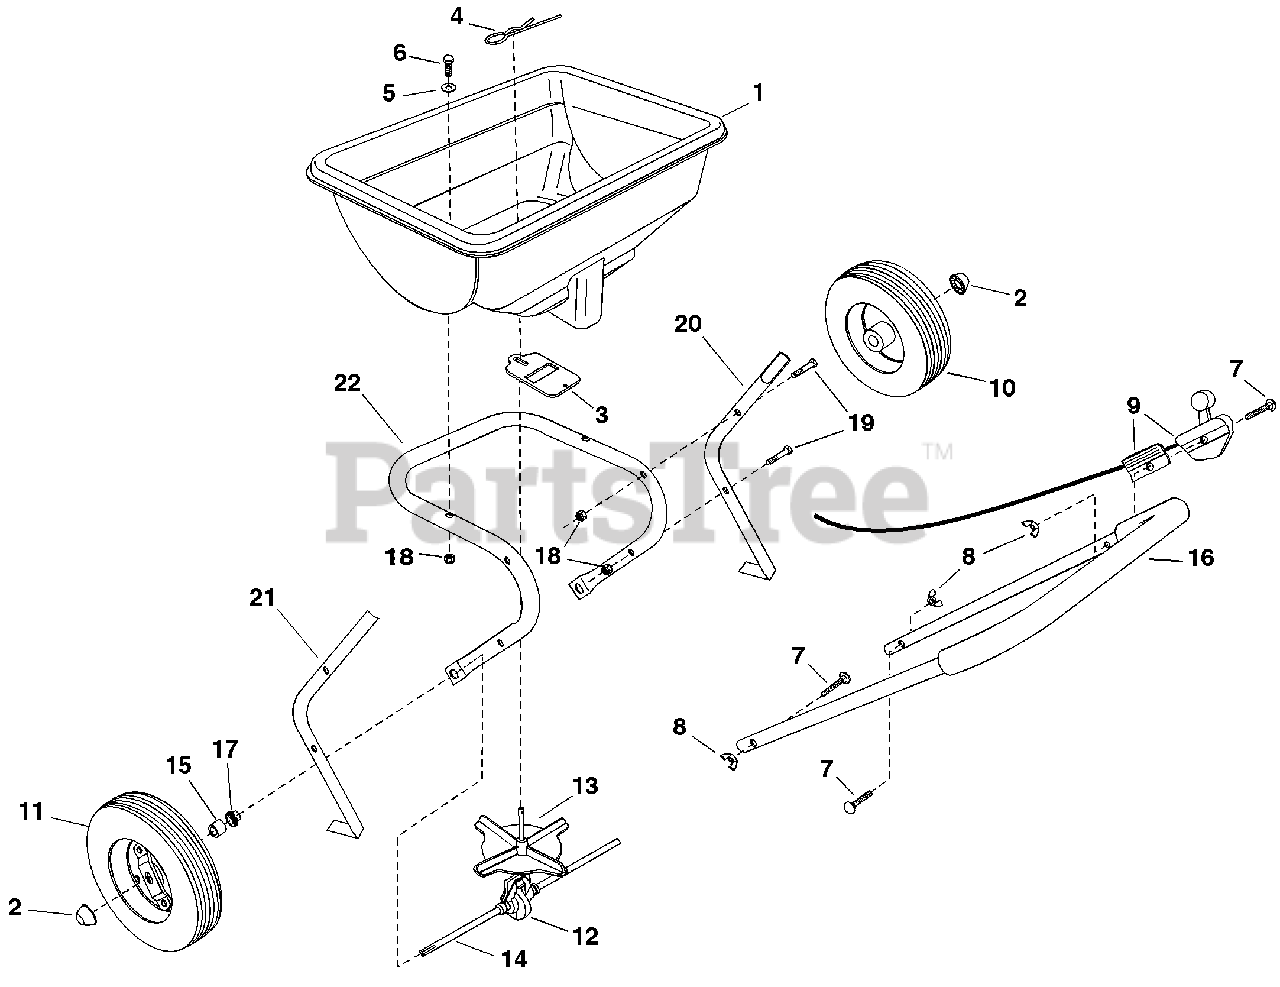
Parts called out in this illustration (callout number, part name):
2	Hub Cap
3	Flow Slide
4	Hairpin Agitator
5	Washer, 1/4 Std
6	Hex Bolt, 1/4-20 x 1-1/2"
7	Carriage Bolt 1/4-20 x 2"
8	Wing Nut, Nylon 1/4-20
9	Control Cable Assembly
10	Wheel & Tire Assembly
11	Wheel & Tire Assembly /w Drive
12	Gearbox Assembly
13	Impeller
15	Plastic Spacer
16	Handle Tube
17	Hex Flange Bearing
18	Nut, Nylock 1/4"
19	Hex Bolt, 1/4-20 x 2"
20	Leg Tube, R.H.
21	Leg Tube, L.H.
22	Frame Tube
